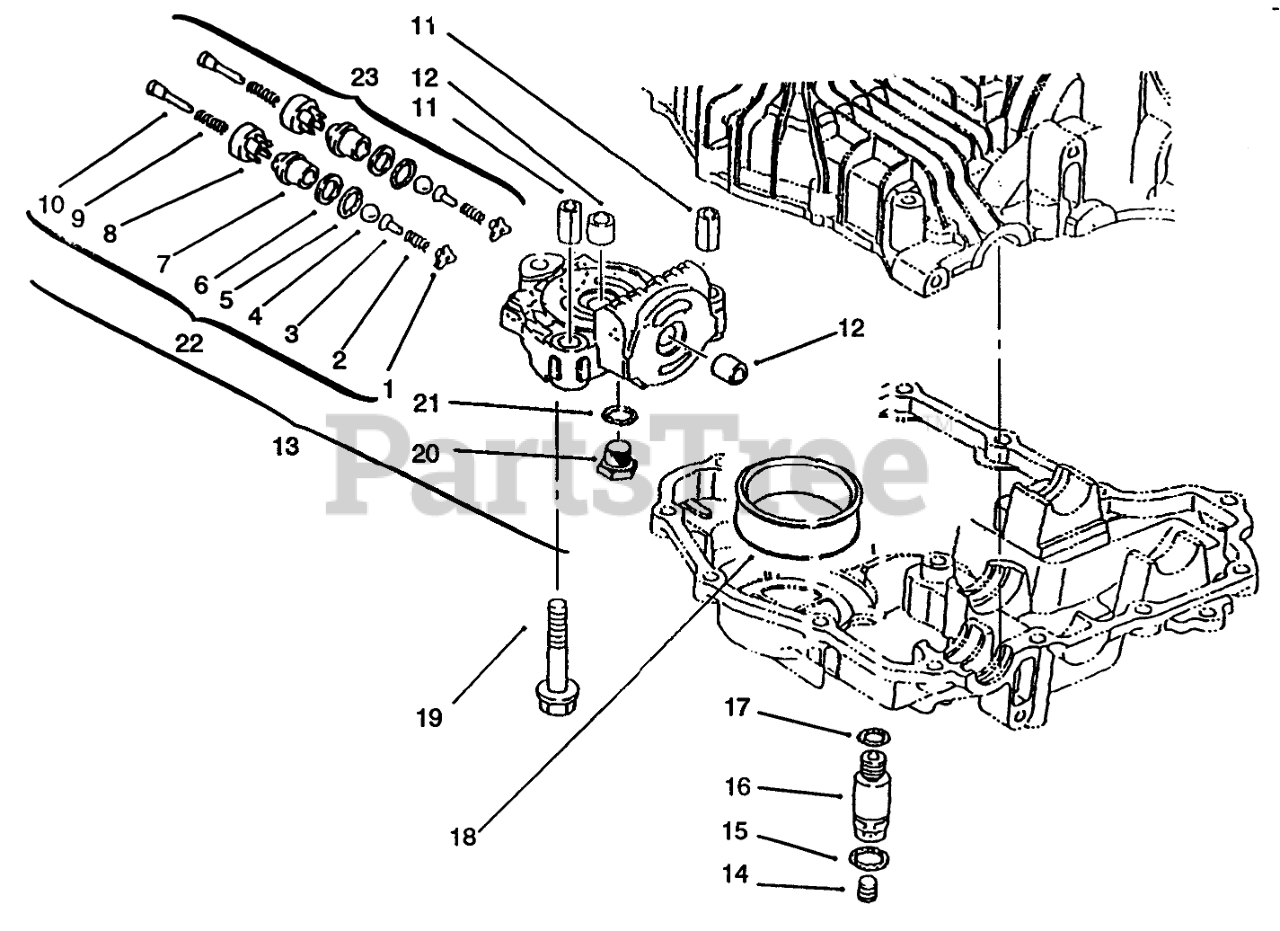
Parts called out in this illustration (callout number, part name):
1	Holder-Bypass (Only On: 72083, 72043, 72103, 72063)
5	Packing (Only On: 72083, 72043, 72103, 72063)
6	Ring-Back Up (Only On: 72083, 72043, 72103, 72063)
11	Pin-Knock (Only On: 72083, 72043, 72103, 72063)
12	Bushing (Only On: 72083, 72043, 72103, 72063)
13	Case INC 11-12 & 20-23 (Only On: 72083, 72043)
14	Plug (Only On: 72083, 72043, 72103, 72063)
15	Packing (Only On: 72083, 72043, 72103, 72063)
16	Connector (Only On: 72083, 72043, 72103, 72063)
17	Packing (Only On: 72083, 72043, 72103, 72063)
18	Filter (Only On: 72083, 72043, 72103, 72063)
19	Bolt (Only On: 72083, 72043, 72103, 72063)
20	Plug (Only On: 72083, 72043, 72103, 72063)
21	Packing (OnlyOn: 72083. 72043, 72103, 72063)
22	Valve ASM A1 INC 1-10 (Only On: 72083, 72043, 72103, 72063)
23	Valve ASM A2 (Only On: 72083, 72043, 72103, 72063)
